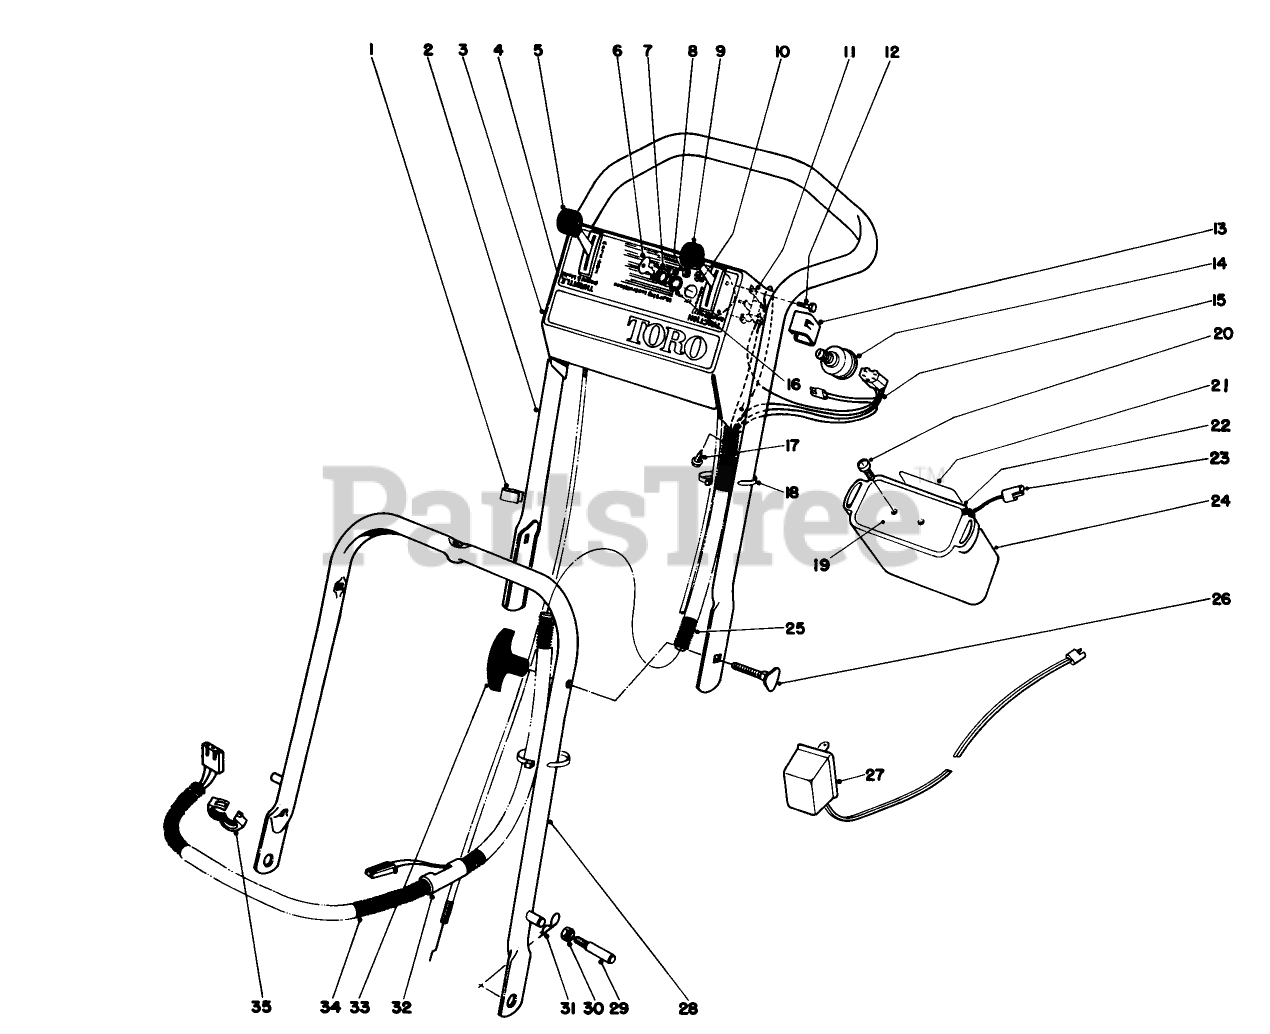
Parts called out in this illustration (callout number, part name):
2	UPPER HANDLE
8	NUT-HEX
10	WASHER-FLAT
11	CONTROL SWITCH
12	DISC PREC HUSKY
14	SWITCH-STARTER
16	WASHER-LOCK
17	SCREW-HWHTF
18	TIE-CABLE
22	Battery Pack (Incl. Ref. #22-26)
26	SCREW-HANDLE
29	HANDLE PIN
31	PIN-COTTER, HAIR
